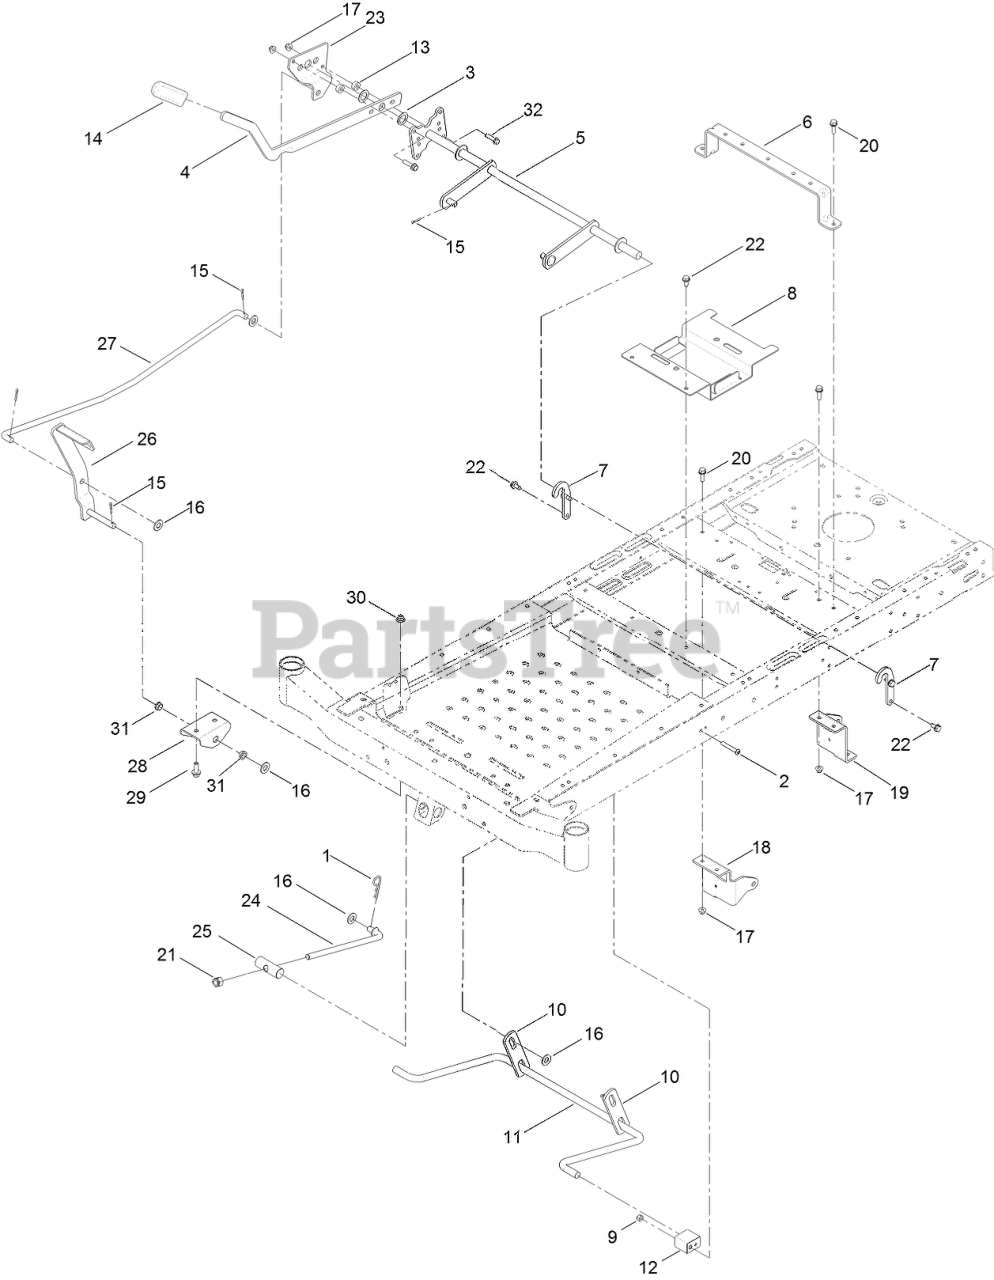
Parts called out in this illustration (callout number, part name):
1	PIN-COTTER
2	SCREW-HSBH
3	WASHER-THRUST
4	LEVER-LIFT
5	LIFT-DECK, WIDE
6	BRACE-SEAT, REAR
7	BRACKET-LIFT
8	BRACKET-BATTERY
9	NUT-LOCK, NI
10	LINK-LIFT
11	ARM-LIFT, REAR (WIDE)
12	BLOCK-PIVOT
13	SPACER
14	GRIP-LEVER
15	PIN-COTTER
16	WASHER-FLAT
17	NUT-HF, NI
18	MOUNT-HYDRO, FRONT (RH)
19	MOUNT-HYDRO, FRONT (LH)
20	SCREW-HHF
21	NUT-HEX
22	SCREW-HWHTF
23	PLATE-FOOTLIFT
24	ROD-TRUNION
25	PIN-PIVOT
27	ROD-FOOTLIFT
28	BRACKET-FOOTLIFT
29	SCREW-HHF
30	NUT-HF, NI
31	BUSHING-FLANGE
32	SCREW-HHF
